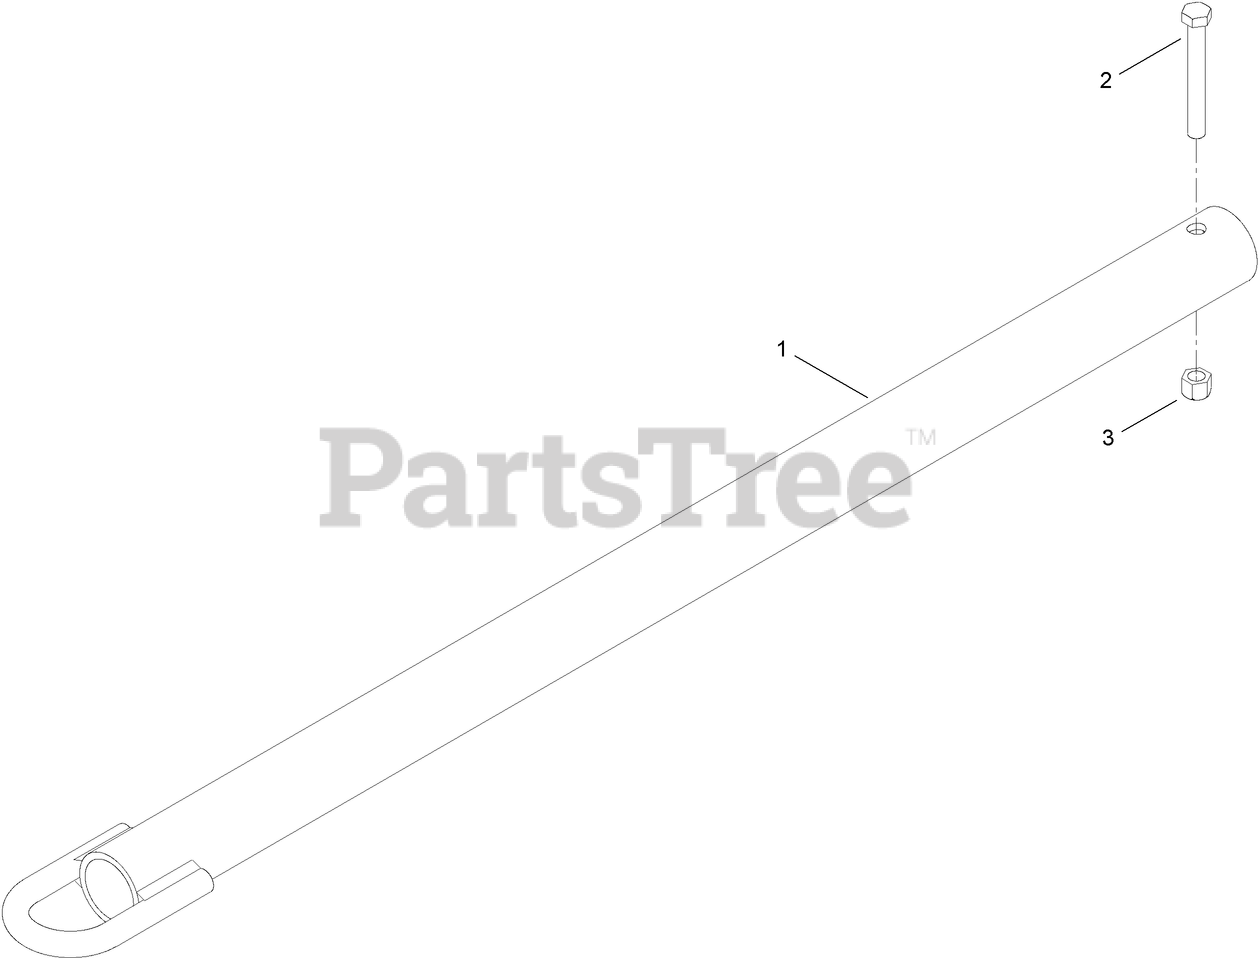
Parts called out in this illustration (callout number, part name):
1	POLE-TOW, 50 INCH (PINTEL)
2	SCREW-HH
3	NUT-LOCK, NI
